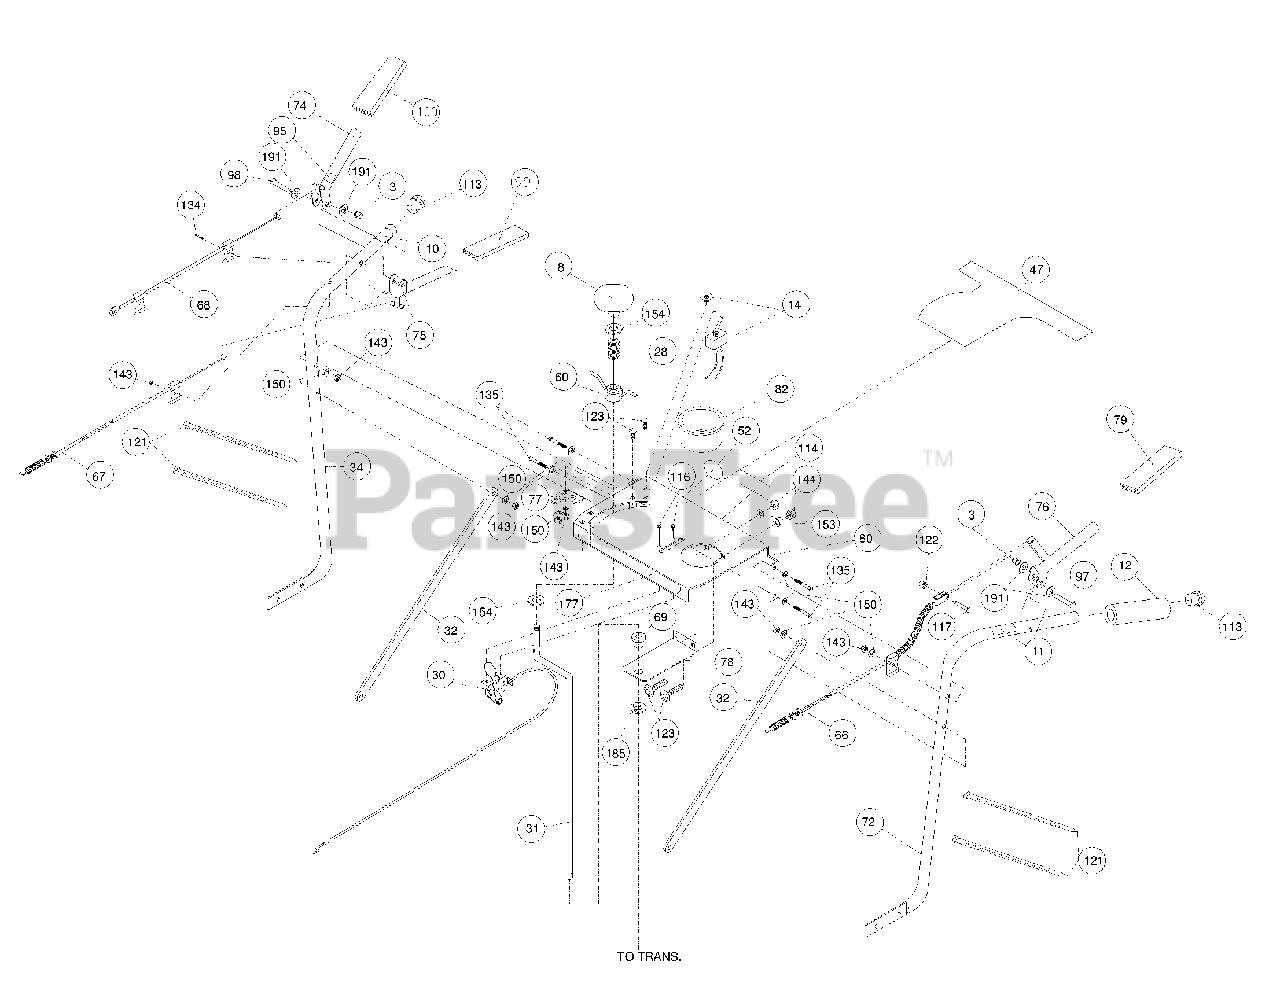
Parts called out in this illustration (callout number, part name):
3	PALNUTS 3/8”
8	KNOB 1/2” THREAD
10	LABEL CLUTCH DRIVE
11	LABEL BLADE DRIVE
12	GRIP HANDLE 1” x 7”
14	SWITCH ELECTRIC W/ NUT
28	SPRING COMPRESSOR 1/2”
30	CONTROL THROTTLE POS
31	ROD SHIFT LINKGAGE
32	BAR HANDLE BRACE FM
34	HANDLE RH FM
47	LABEL CONSOLE
52	LABEL READ MANUAL
60	SHIFT LOCK HANDLE FM WA
66	CABLE CLUTCH BLADE FM
67	CABLE CLUTCH DRIVE FM
68	CABLE CLUTCH BRAKE FM
69	BUSHING NYLON
72	HANDLE LH FM
74	LEVER CONTROL BRAKE FM
75	LEVER CONTROL DRIVE FM
76	LEVER CONTROL BLADE FM
77	PLATE REV LOCK OUT
78	BRACKET SHIFT PIVOT FM
79	GRIP LEVER ORANGE
80	CONSOLE FM W/ LABELS
82	CUP HOLDER
95	LABEL PUSH TO RELEASE
97	CLEVIS PINS 3/8 - 1.625
98	CLEVIS PINS 3/8 - 2.125
99	GRIP LEVER 0.125-1.00-3.75
100	GRIP LEVER 0.125-0.75X3.75
113	PLUG TUBE INSERT 1”
114	LABEL EAR-EYE-BREATHE
116	SCREW 1/4” - 20 X 5/8
117	PIN CLEVIS 5/16-24
122	PAL NUTS 5/16”
123	BOLT CARRIAGE 5/16-18 X 3/4
134	SCREW CAP 5/16-18 X 2
135	SCREWCAP 5/16-18 x 2 1/4
143	NUT LOCK 5/16-18 NYLON
144	NUT LOCK 3/8-16 NYLON
150	WASHER 1/4” FC
153	WASHER 5/16 SAE
154	WASHER 1/2” SAE ZP
177	LABEL BGI OVAL FM
185	RETAINING RING EXTERNAL
191	WASHER 5/16” FC
